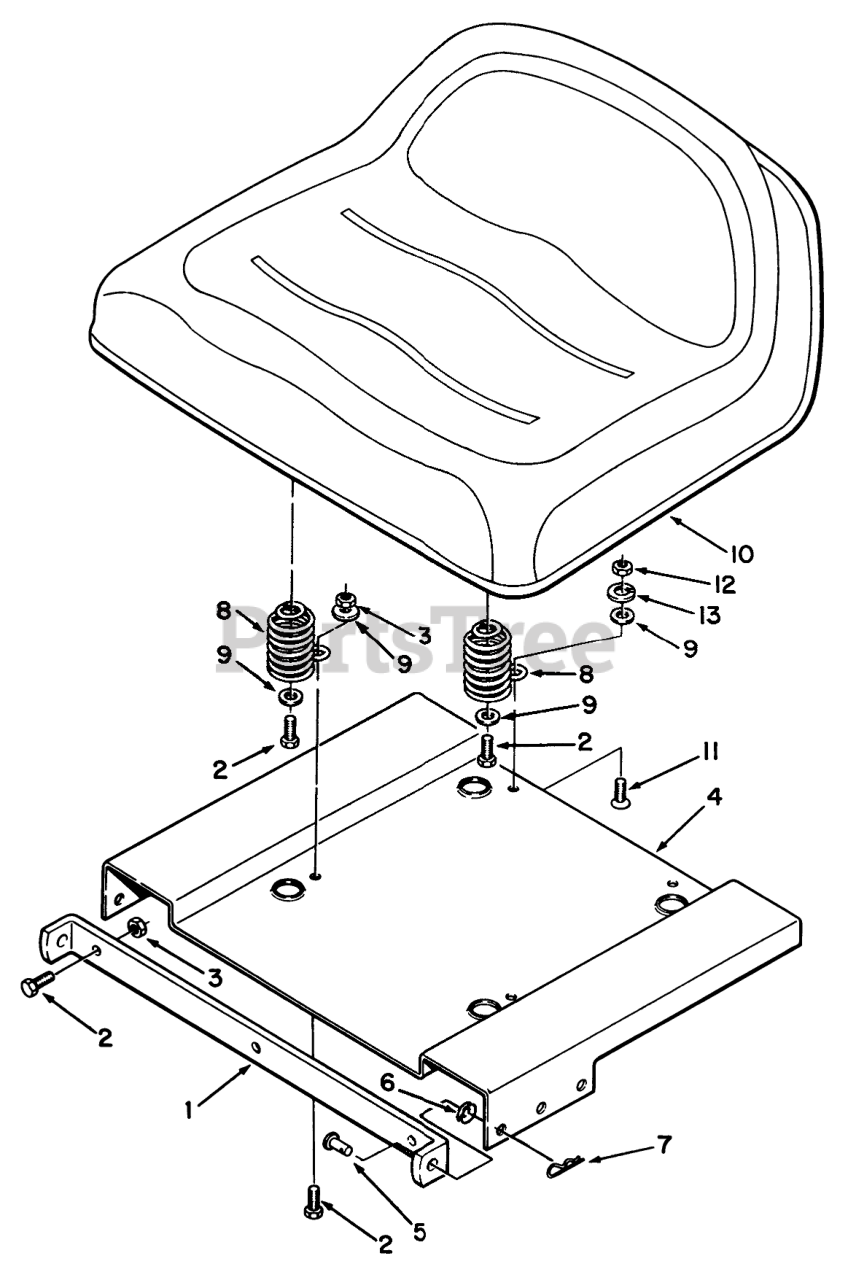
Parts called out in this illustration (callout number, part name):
1	BRACKET - SEAT MO R
2	SCREW-HH
3	NUT-LOCK, NI
4	PLATE-SEAT PIVOT R
6	WASHER-SPRING
7	Hairpin
8	SPRING SEAT
9	WASHER-PLAIN
10	SEAT V-550 LESS LOGO
11	Screw
12	NUT-HEX
13	WASHER-LOCK
